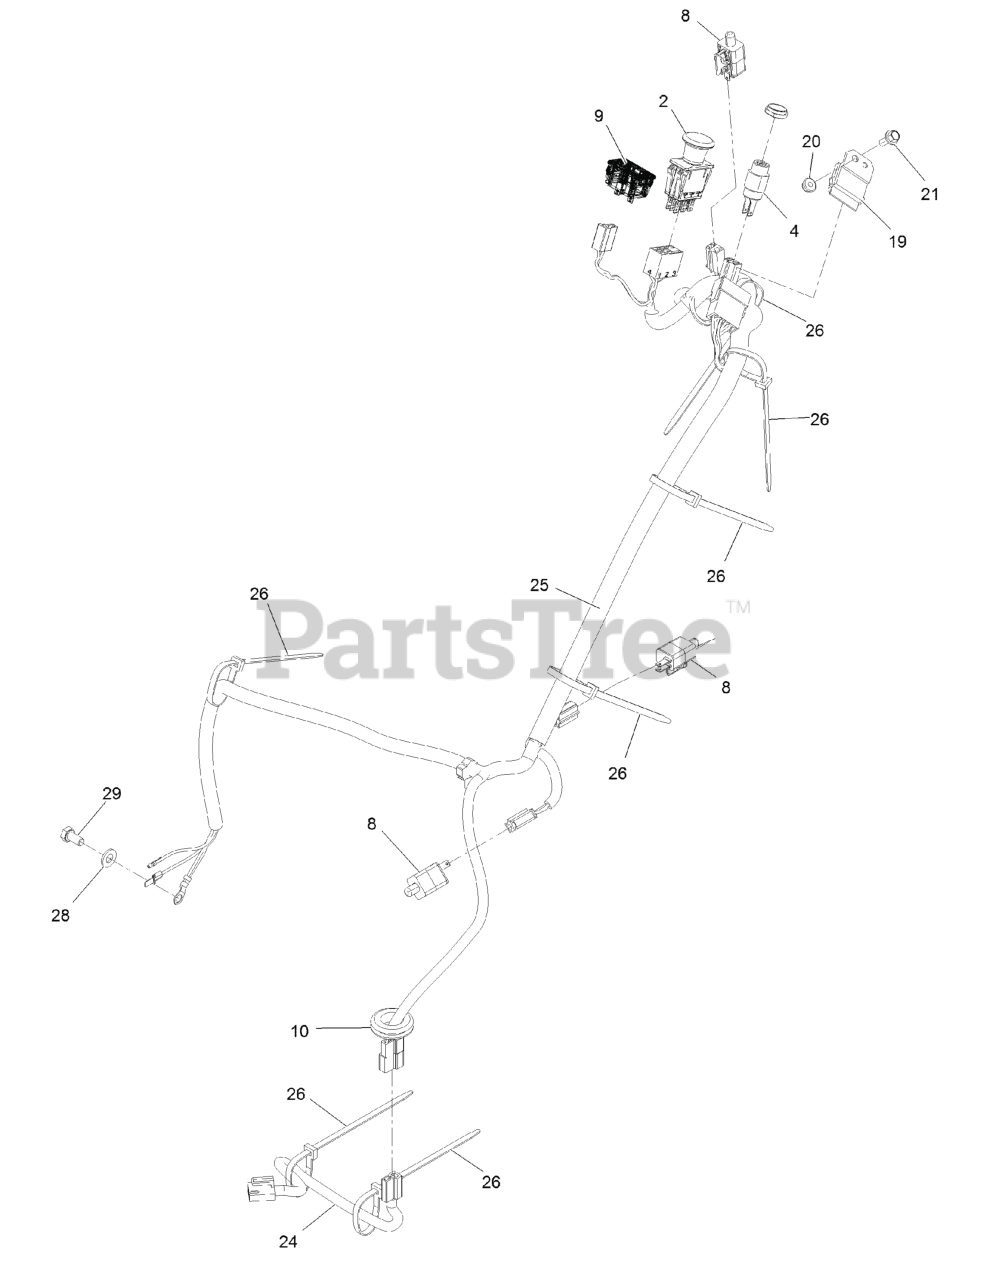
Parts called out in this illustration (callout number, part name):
2	SWITCH-PTO
4	SWITCH & KEY (INCLUDES NU
4	NUT-SWITCH, IGNITION
9	METER-HOUR
10	GROMMET
19	MODULE-INTERLOCK
21	SCREW-HEAD, FLANGE
24	HARNESS-CLUTCH PIGTAIL
25	HARNESS-MAIN
26	TIE-PLASTIC
28	WASHER-PLAIN
29	SCREW-HH
